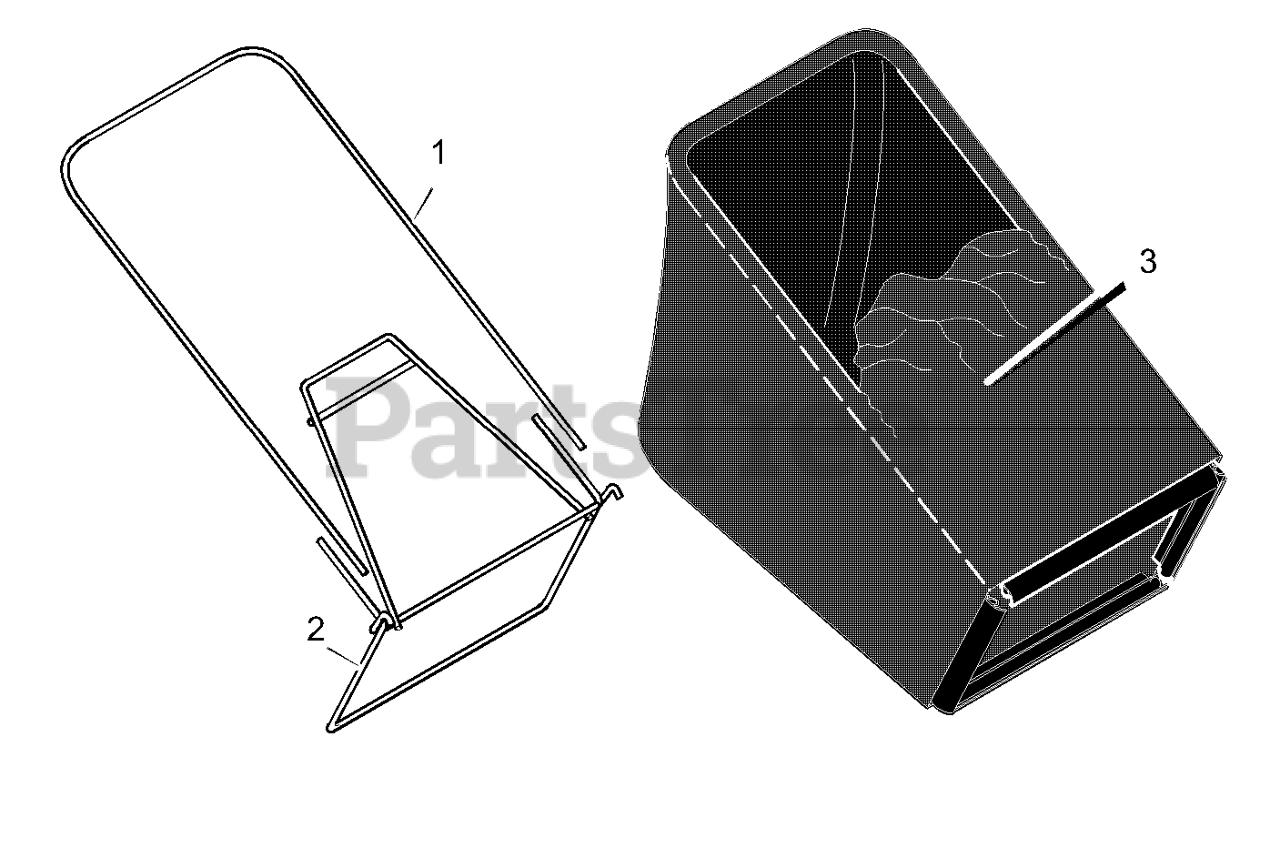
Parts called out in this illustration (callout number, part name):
1	Frame, Top
2	Frame Assembly
3	Bag, Cloth
